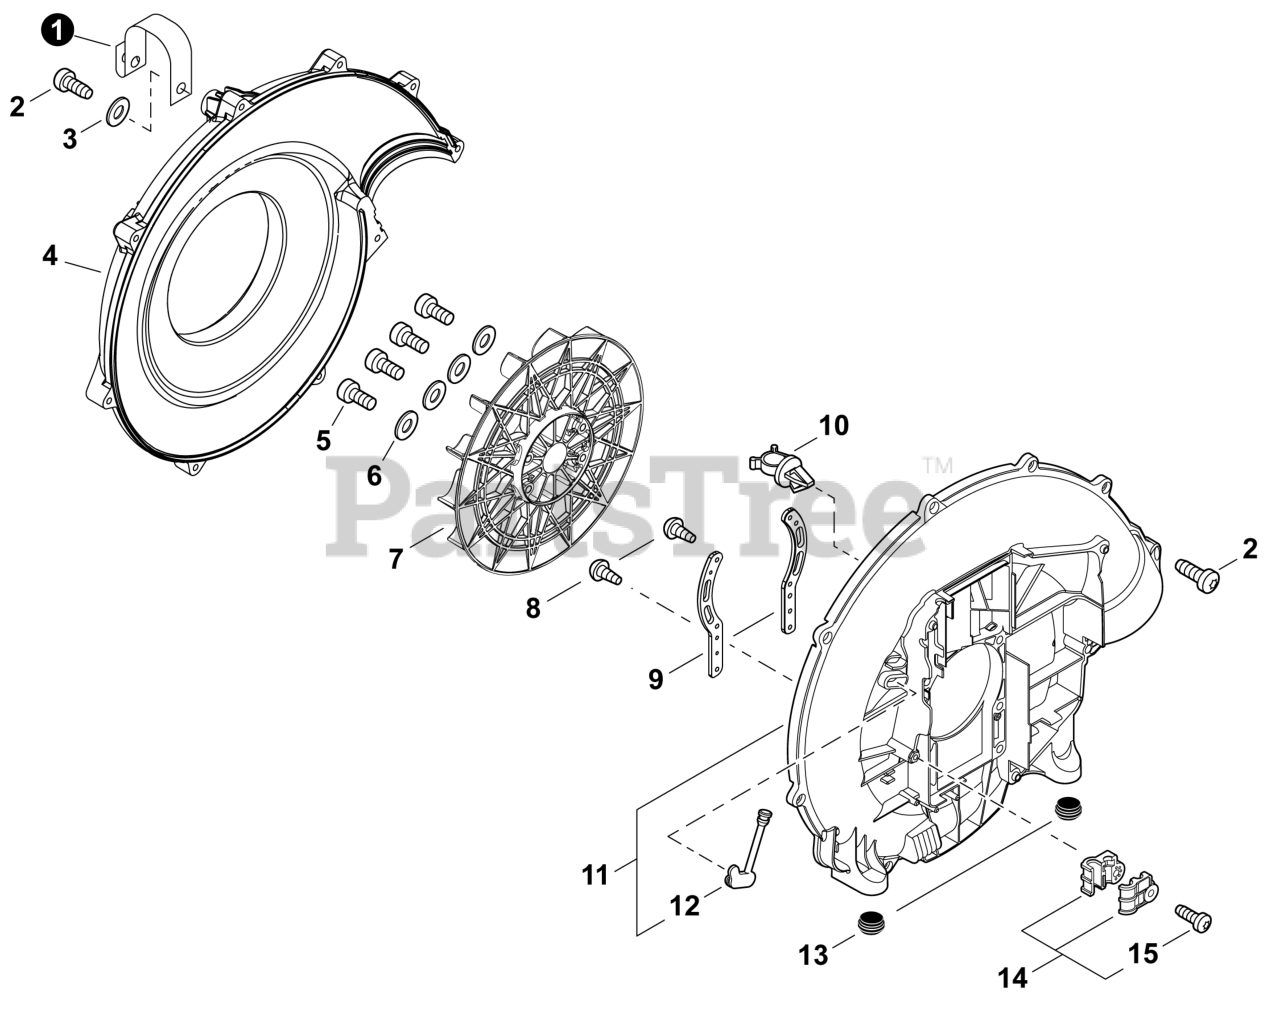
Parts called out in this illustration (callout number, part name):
1	STRAP, SAFETY 1.2x100
2	BOLT, TORX 5x20
3	WASHER 5.5x16x2T
4	COVER, FAN
5	BOLT, TORX 5x30
6	WASHER 5.5x16x2T
7	FAN, BLOWER
8	SCREW TAPPING 3x12
9	BRACKET, ENGINE
10	CLIP, CABLE
11	FAN CASE SET
12	GROMMET
13	CUSHION
14	CABLE HOLDER SET
15	BOLT, TORX 5x25
